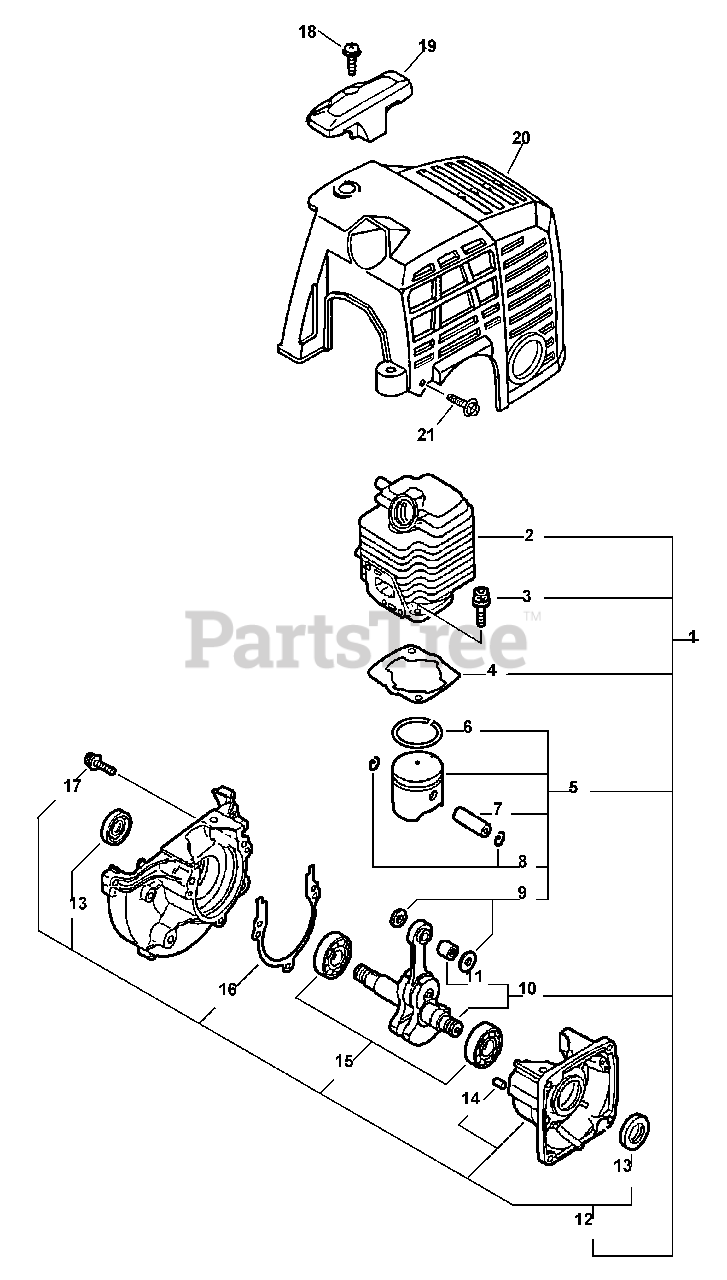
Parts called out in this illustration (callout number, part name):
1	SHORT BLOCK ES-2100;PB-2100
2	CYLINDER
3	BOLT 5×22
4	GASKET, CYLINDER
5	PISTON KIT
6	RING, PISTON
7	PIN, PISTON 8
8	RING, SNAP
9	WASHER, THRUST
10	CRANKSHAFT ASSY
11	BEARING, NEEDLE
12	CRANKCASE KIT
13	SEAL, OIL 12
14	PIN, LOCATING 4×8
15	BEARING, BALL 6201
16	GASKET, CRANKCASE
17	BOLT 5×28
18	SCREW 5×16
19	GUARD, TOP
20	COVER, ENGINE
21	BOLT 4×16
